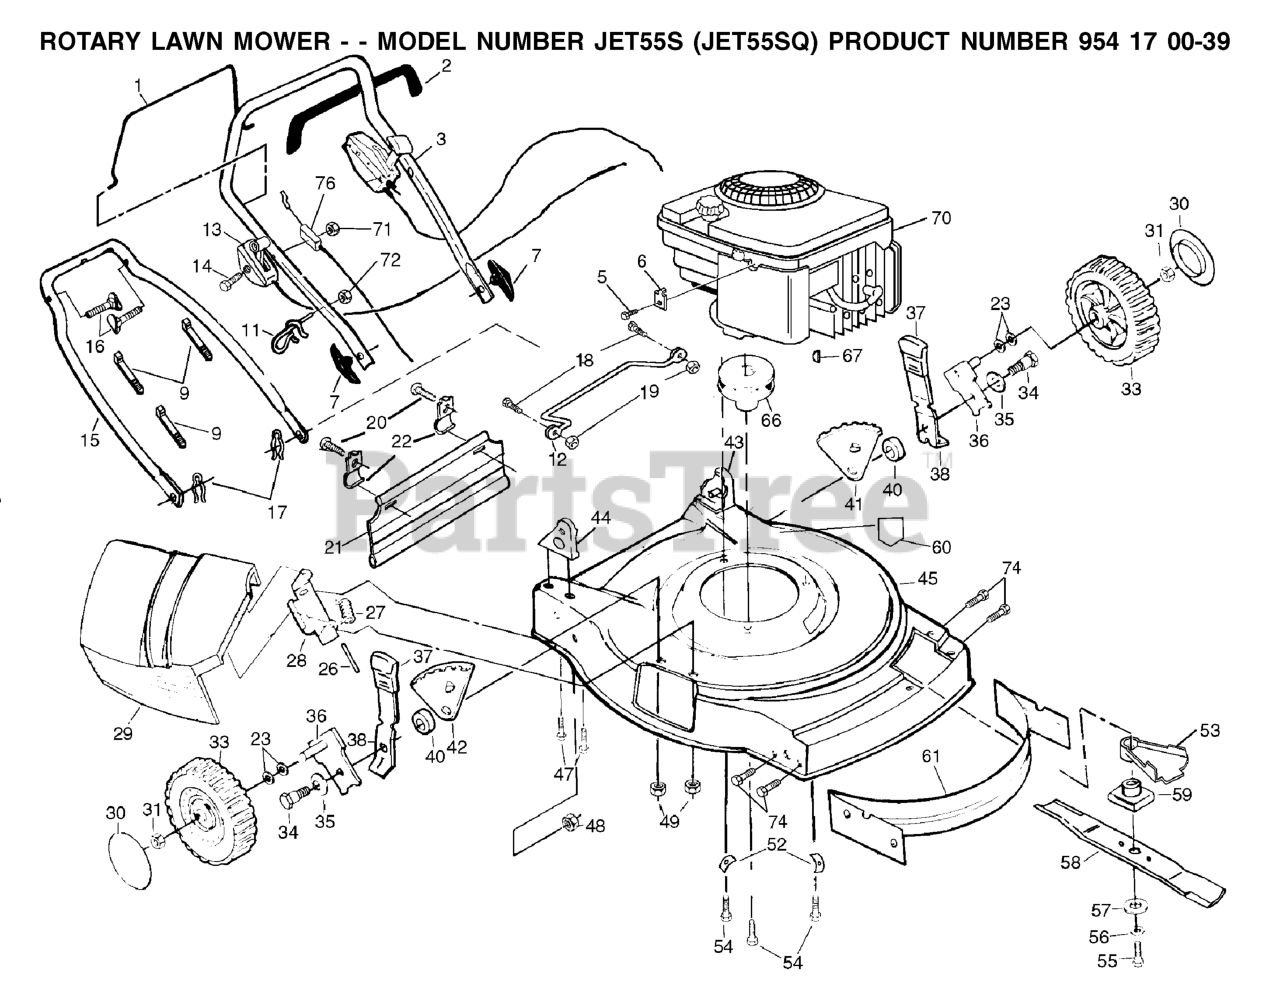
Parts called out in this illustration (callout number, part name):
1	BAIL.CNTRL.DLX.CK
2	GRIP.HANDLE.FOAM
3	HANDLE.UP.DLX.COMF.W/GRIP.GREY
5	SCREW.HEX.HEAD.WASHER.10-16
6	WASHER
7	HANDLE KNOB
9	TIE GUIDE
11	ROPE, GUIDE
13	THROTTLE CONTROL
14	SCREW 1/4-20 X 2.12
15	LOWER HANDLE
16	HANDLE BOLT
17	HAIRPIN COTTER
18	REPL BY 817 02 10-08
20	TAPPING SCREW
21	REAR SKIRT
22	BRACKET DEFL PM
23	WAVE WASHER
26	ROD.HINGE.COMBI-C
28	BRACKET PM
29	DISCHARGE GUARD
30	HUBCAP.8".GREY
31	HEX FLANGE LOCKNT
33	WHEEL.8X2.PR.LP.RAD.GREY
34	BOLT
35	WASHER.BELLEVILLE (3 2 LB)
36	AXLE ARM
37	SELECTOR KNOB
40	RP SPACER HT ADJ
41	WHL ADJ BRKT RF/LR
42	WHL ADJ BRKT LF/RR
43	HANDLE BRACKET ASM. LH
44	HANDLE BRACKET ASM. RH
47	SCREW.5/16-18X3/4
48	LOCKNUT PM
49	NUT
52	WASHER.ENGINE.BZP
53	DEBRIS SHIELD
54	BOLT 3/8-16X1-1/8
55	SCREW, HEX HD 3/8-24 X 1-3/8
56	LOCKWASHER
57	WASHER,HARDEN
59	BLADE ADAPTOR
60	DECAL MOWER CUT/FINGER
66	ENGINE.PULLEY.FWG
67	HI PRO KEY PM WSL
71	NUT
72	NUT
74	SCREW 1/4X20
76	ENGINE ZONE CONTROL CABLE
